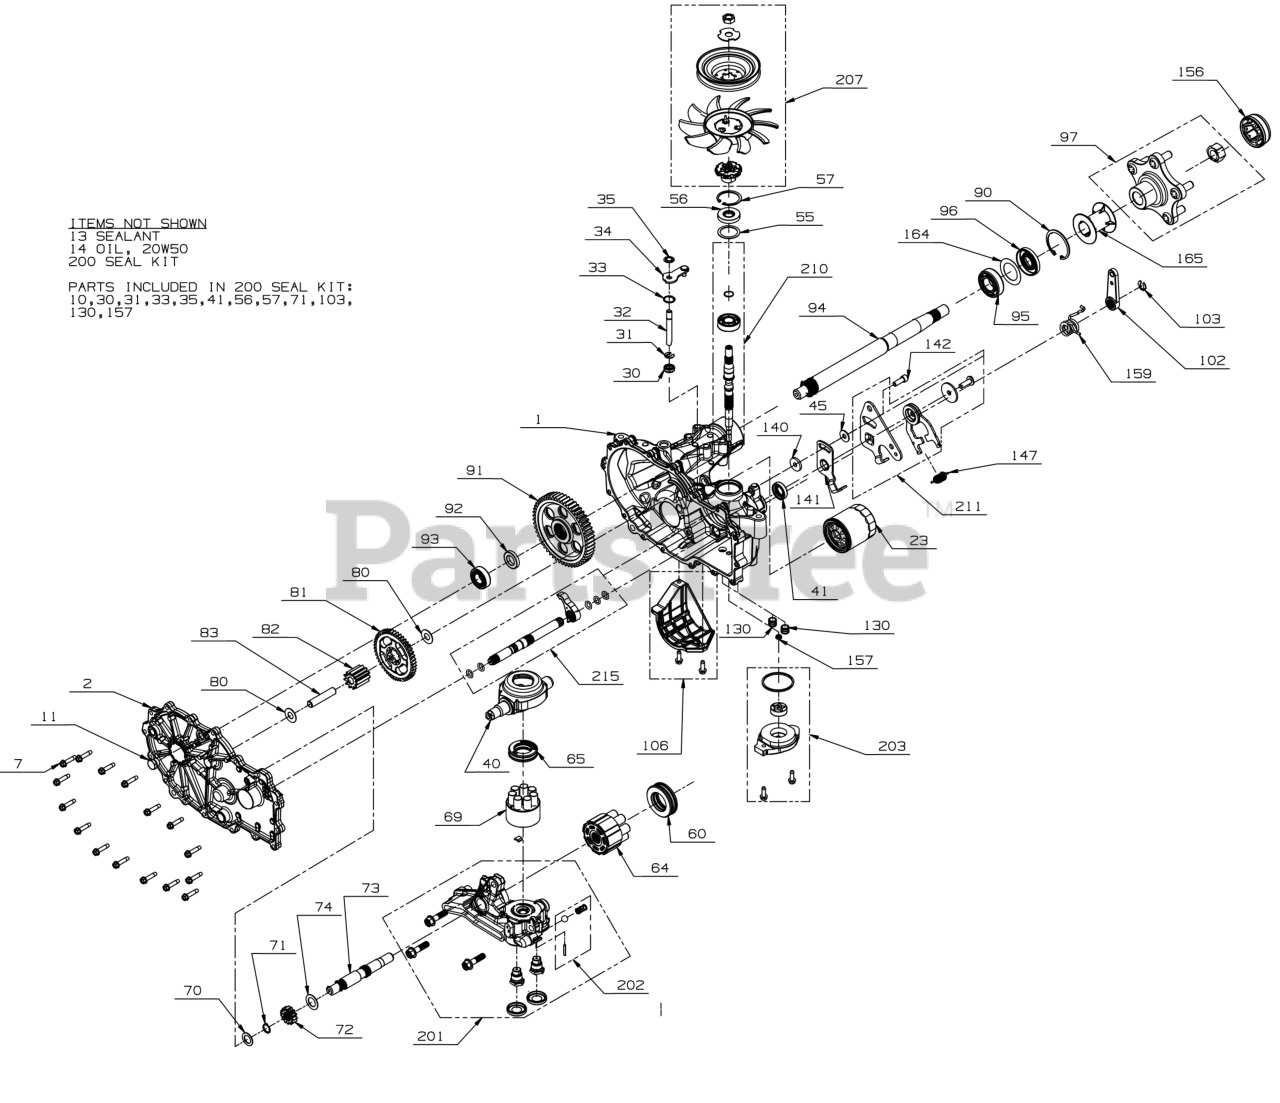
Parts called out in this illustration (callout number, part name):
1	KIT - HOUSING MAIN LH CNTL
2	KIT - SIDE COVER LH
7	SCREW-WASHER HEAD
11	VENT PLUG
13	SEALANT-HOUSING
23	OIL FILTER
30	SEAL-LIP .375 X .75 X .25
31	RETAINING RING
32	BYPASS RODS
33	RETAINING RING
34	ARM-BYPASS
35	RETAINING RING
40	SWASHPLATE-TRUNNION
45	FLAT WASHER
55	WASHER 1.23X1.56X
57	RETAINING RING
60	THRUST BEARING
64	CYLINDER BLOCK ASSEMBLY
65	THRUST BEARING
69	BLOCK KIT-CYLINDER
70	FLAT WASHER
71	RETAINING RING
72	GEAR - 13 TOOTH STEEL
73	MOTOR SHAFT
74	MOTOR SHAFT WASHER
81	GEAR - 46 TOOTH
82	GEAR-11 T
83	PIN-JACKSHAFT
90	RETAINING RING
91	GEAR - 54 TOOTH
92	SPACER .75X1.32X.257
93	BALL BEARING
94	AXLE SHAFT
95	BALL BEARING
97	5 BOLT HUB KIT
102	BRAKE LEVER
103	RETAINING RING
106	FILTER GUARD KIT
130	TUBE-CHARGE TRIPLE O-RING
140	SPACER .32 x 1.005 x .179
141	ARM-NEUTRAL (LH)
142	SCREWS KIT-RTN
147	EXTENSION SPRING
156	COVER-NUT
157	KIT-GEROTOR SEAL
159	TORSION SPRING CW
165	TUBE-AXLE 2.03
200	SEAL KIT
201	CENTER SECTION KIT (LH)
202	KIT-CHARGE RELIEF
203	CHARGE KIT
207	FAN & PULLEY KIT
209	PULLER KIT-HUB
210	INPUT SHAFT KIT
211	RETURN KIT-NEUTRAL (LH) ZT2800 RZT
215	OUTPUT SHAFT KIT (LH)
